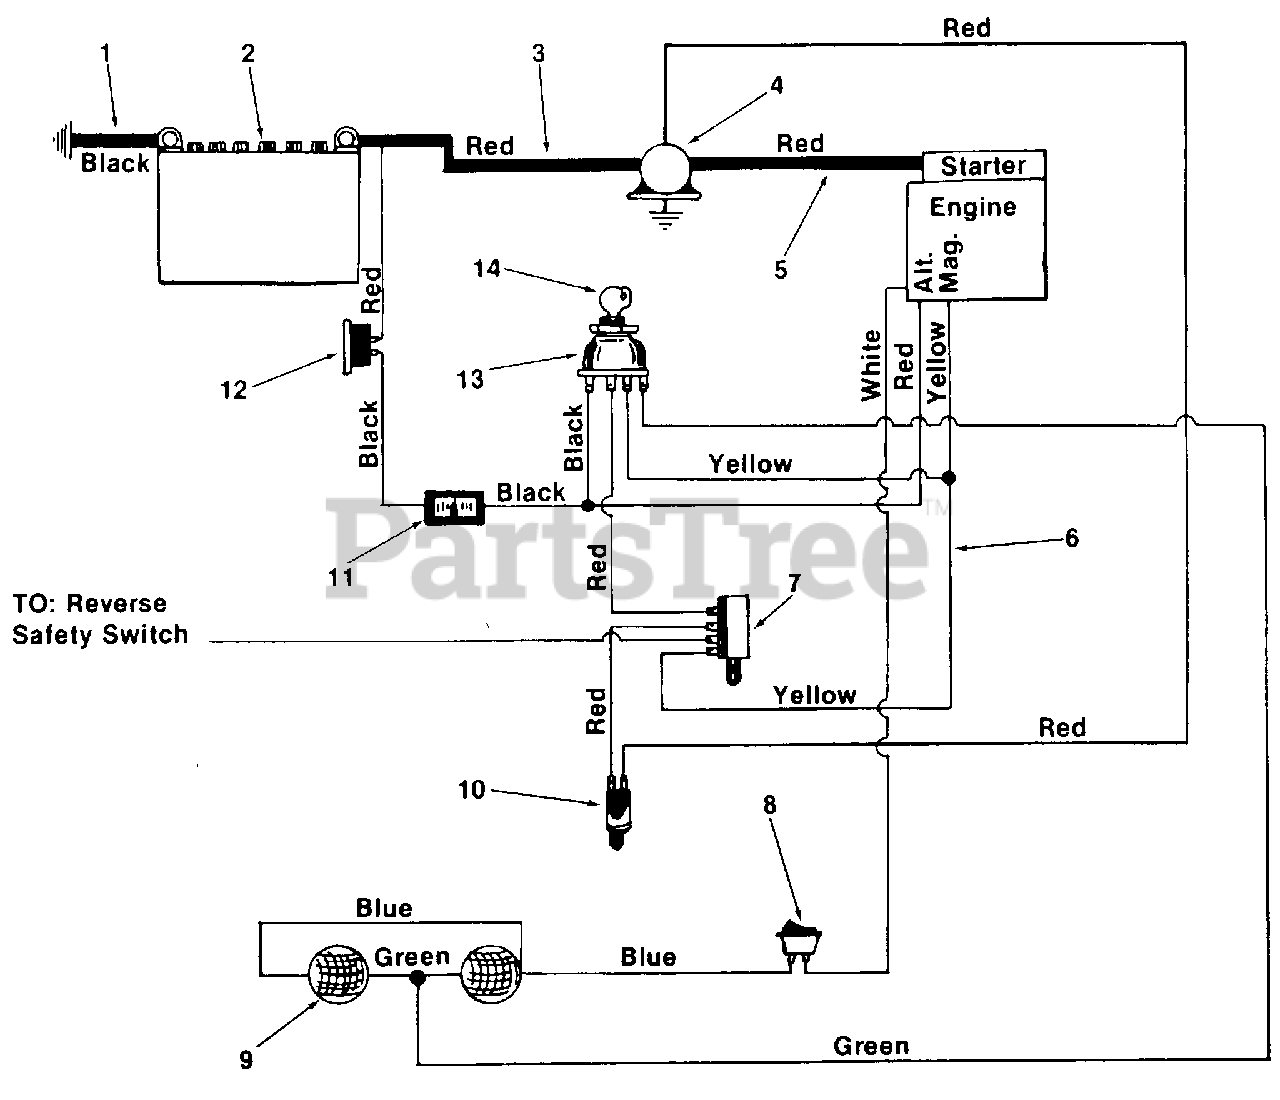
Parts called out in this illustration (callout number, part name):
1	Electric Ground Wire (Black Negative)
2	12V-Battery
3	Electric Wire (Red Positive)
4	Solenoid
5	Electric Wire
6	Wire Harness
7	Safety Switch (P.T.O.)
8	Light Switch
9	Head Lights
10	Safety Switch (Clutch)
11	Ammeter
12	Circuit Breaker
13	Ignition Switch
14	Ignltion Key
